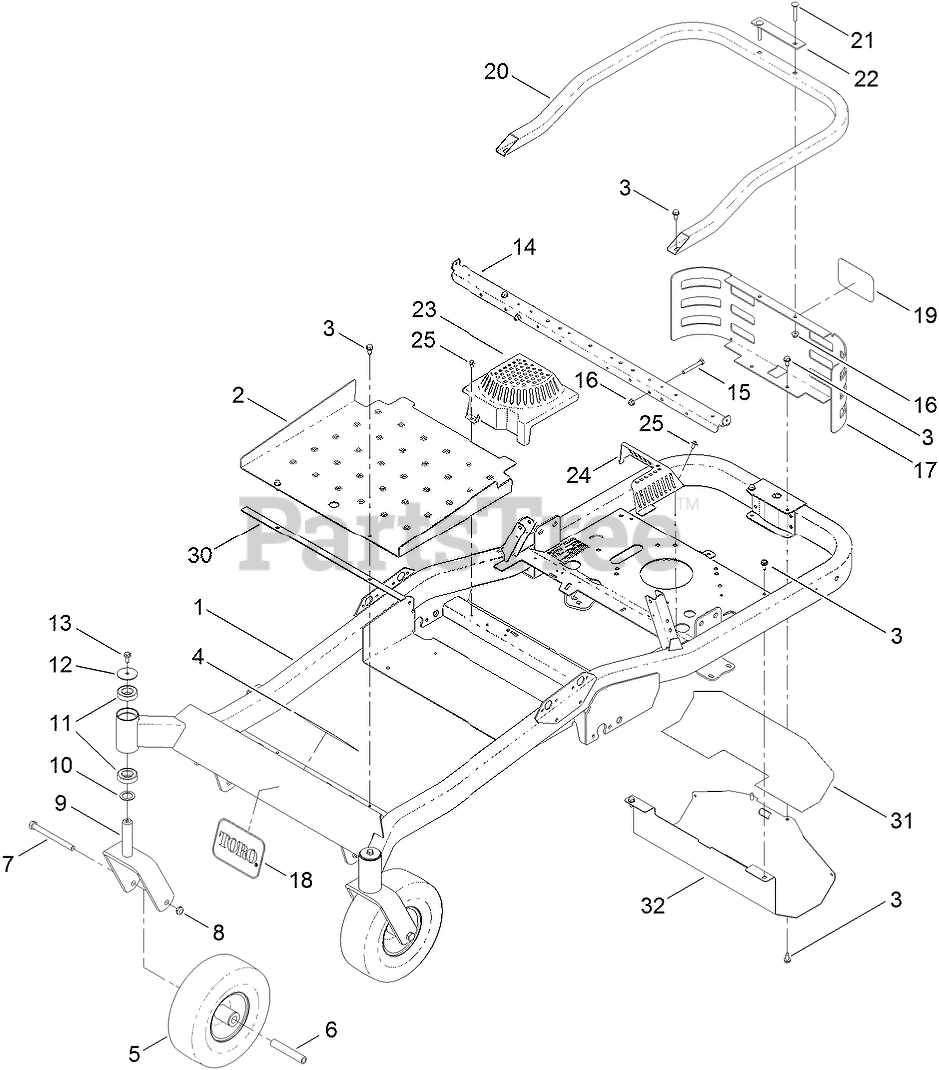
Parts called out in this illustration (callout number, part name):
2	PAN-FLOOR
3	SCREW-HWHTF
4	DECAL-SAFETY
5	TIRE and Wheel ASM (Kenda)
6	BUSHING-SPANNER
7	SCREW-HH
8	NUT-LOCK, NI
9	CASTER FORK ASM
10	WASHER-THRUST
11	BEARING-BALL
12	WASHER
13	SCREW-HHF
14	SUPPORT-SEAT
15	SCREW-HH
16	NUT-HF, NI
17	GUARD-REAR
18	DECAL
20	GUARD-REAR, TUBE
21	Screw-CARR
22	PLATE-SPACER
23	COVER-FAN, RH
24	COVER-FAN, LH
25	SCREW-HHFTF
30	STRIP-VIBRATION, ANTI
31	FOIL-HEAT SHIELD
32	GUARD-MUFFLER
